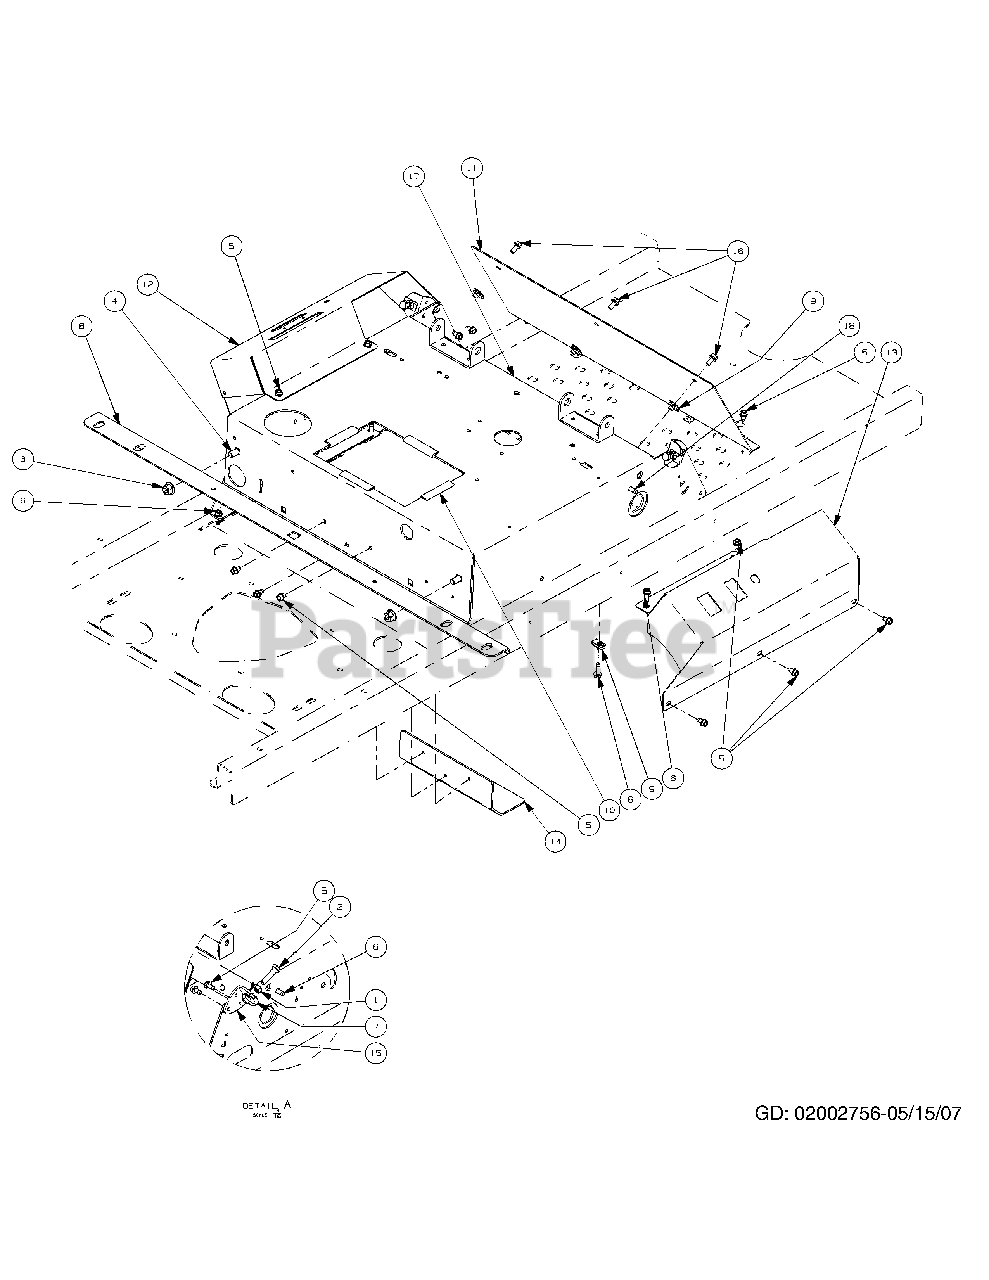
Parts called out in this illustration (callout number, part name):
1	Hex Nut, 5/16-18
2	HHCS, 5/16-18 x 1-1/4
3	Hex Nut, 3/8-16 Flange Lock
4	Carriage Bolt, 3/8-16
5	Screw, 1/4-20 x 1/2
6	Self Tapping Screw, 1/4-20 x .75
7	U-Nut, 5/16-18
8	Front Tank Mounting Bracket
9	U-Nut, 1/4-20
10	Battery Edge Trim
11	Front Panel
12	Left Hand Control Console
13	Right Hand Control Console
14	Battery Bracket
15	Forward/Reverse Stop Bracket
16	Screw, 1/4-20 x 1/2
17	Control Housing Weldment
18	Self Tapping Screw 5/16-18 x .750
